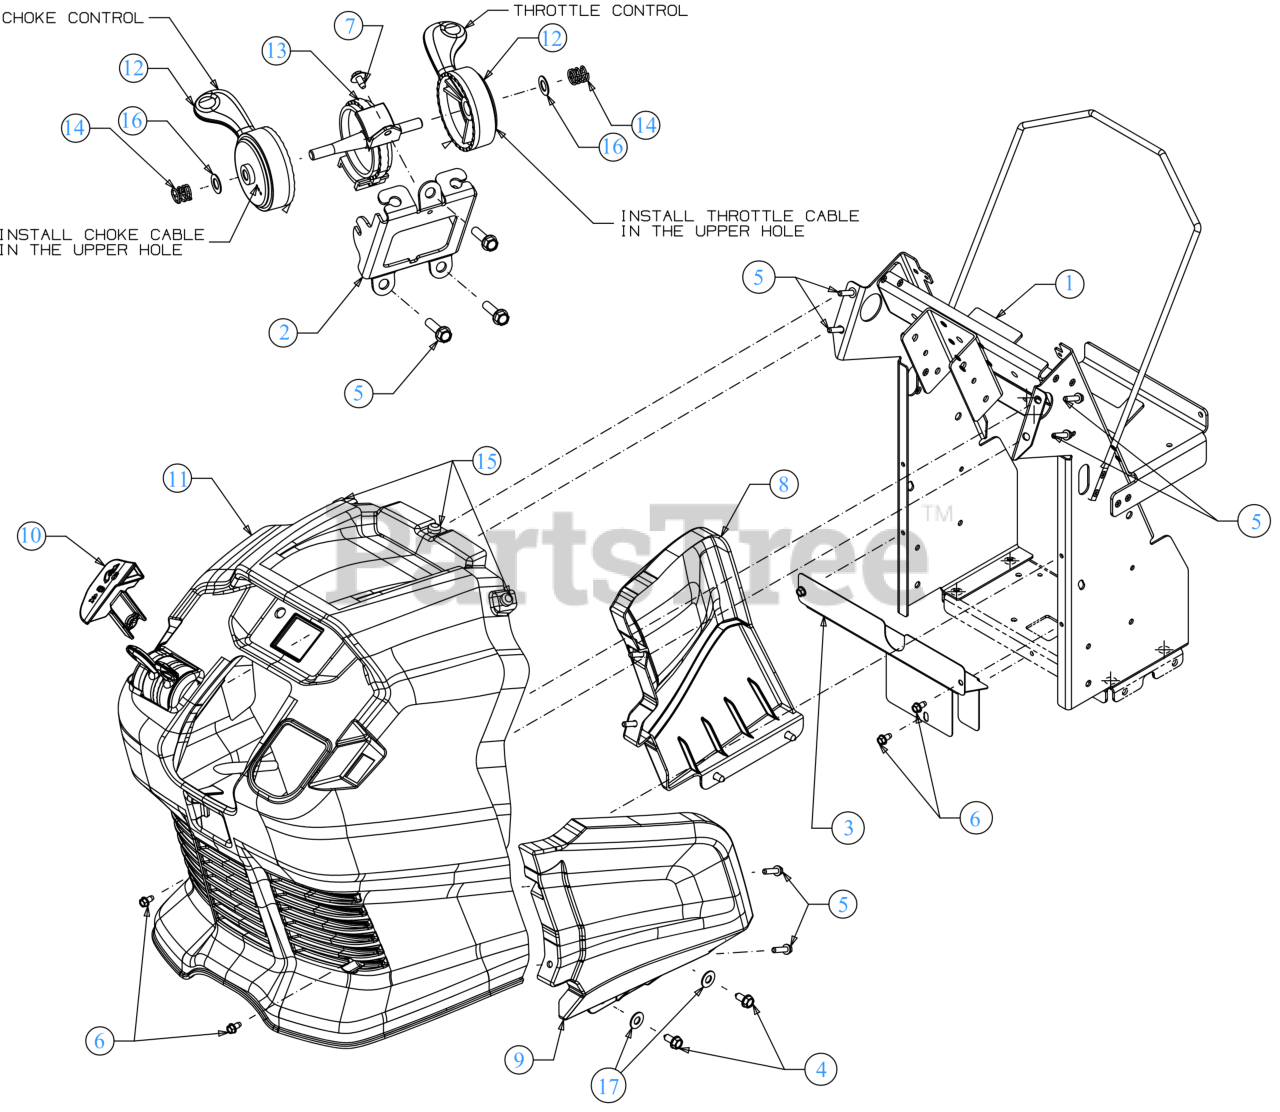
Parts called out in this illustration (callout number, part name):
3	ENGINE SHIELD
4	SCREW 5/16-18 x .750
5	SCREW 5/16-14 x 1
6	SCREW 1/4-20 X.500
7	SCREW #10-16 x .375
8	DASH PANEL LOWER (LH)
9	DASH PANEL LOWER (RH)
10	CRUISE/PARK BRAKE LEVER
11	DASH PANEL
12	THROTTLE/CHOKE CONTROL LEVER
13	THROTTLE/CHOKE INDEX DISC
14	COMPRESSION SPRING
15	BUMPER, .62 DIA x .3
16	FLAT WASHER .344 ID x .62 OD x .033
17	FLAT WASHER.40 ID
